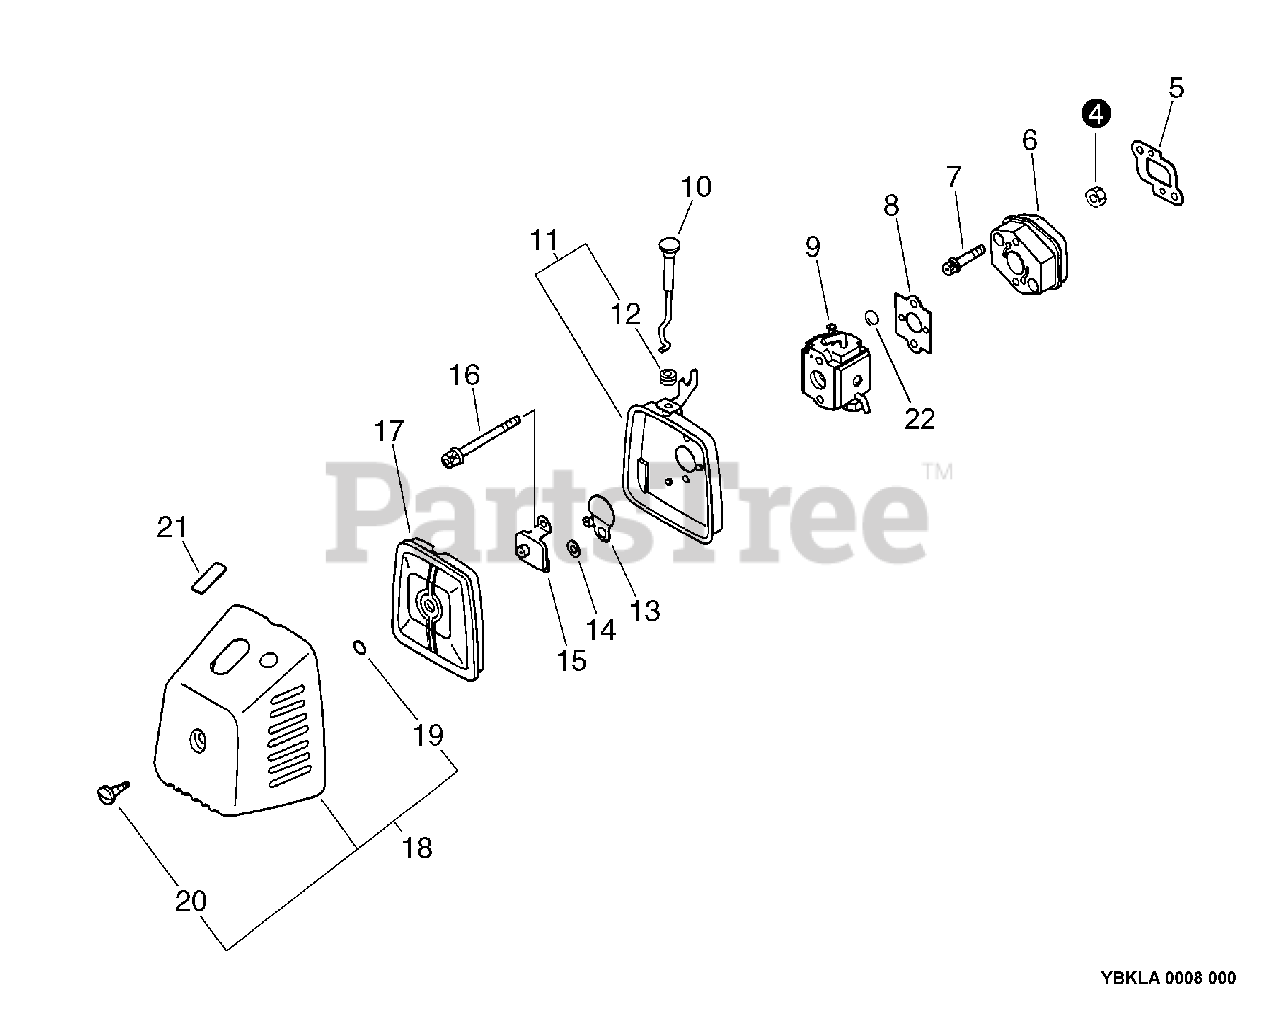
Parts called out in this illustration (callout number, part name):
5	GASKET, INTAKE
6	INSULATOR, INTAKE
7	SCREW - 5X25
8	GASKET, INTAKE
9	CARBURETOR
10	ROD, CHOKE
11	AIR FILTER CASE ASSY
13	SHUTTER, CHOKE
14	WASHER - 5
15	PLATE, PREVENT
16	SCREW - 5X57
17	FILTER, AIR
18	AIR FILTER COVER ASSY
19	O-RING - 4
21	LABEL - CHOKE
